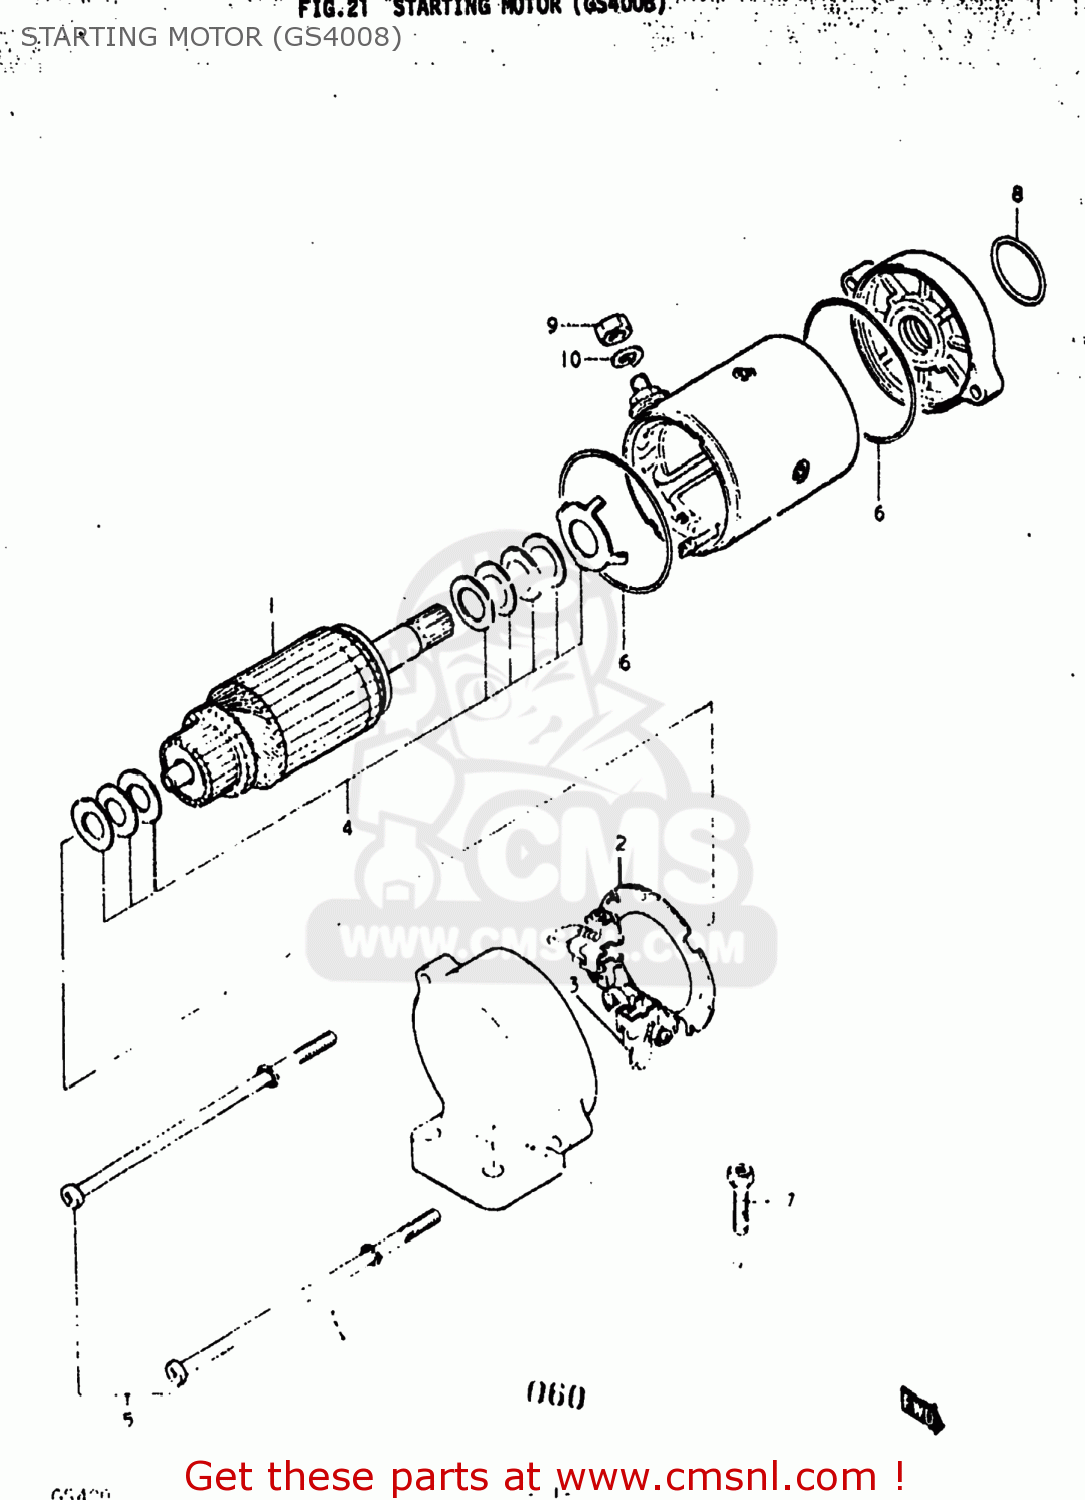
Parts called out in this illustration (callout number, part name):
1	ARMATURE
2	HOLDER ASSY
3	BRUSH SET
4	SHIM SET
5	BOLT,STARTING MOTOR HOUSING
6	O RING
7	SCREW
8	O RING(D:2,ID:24.5)
9	NUT
10	LOCK WASHER
